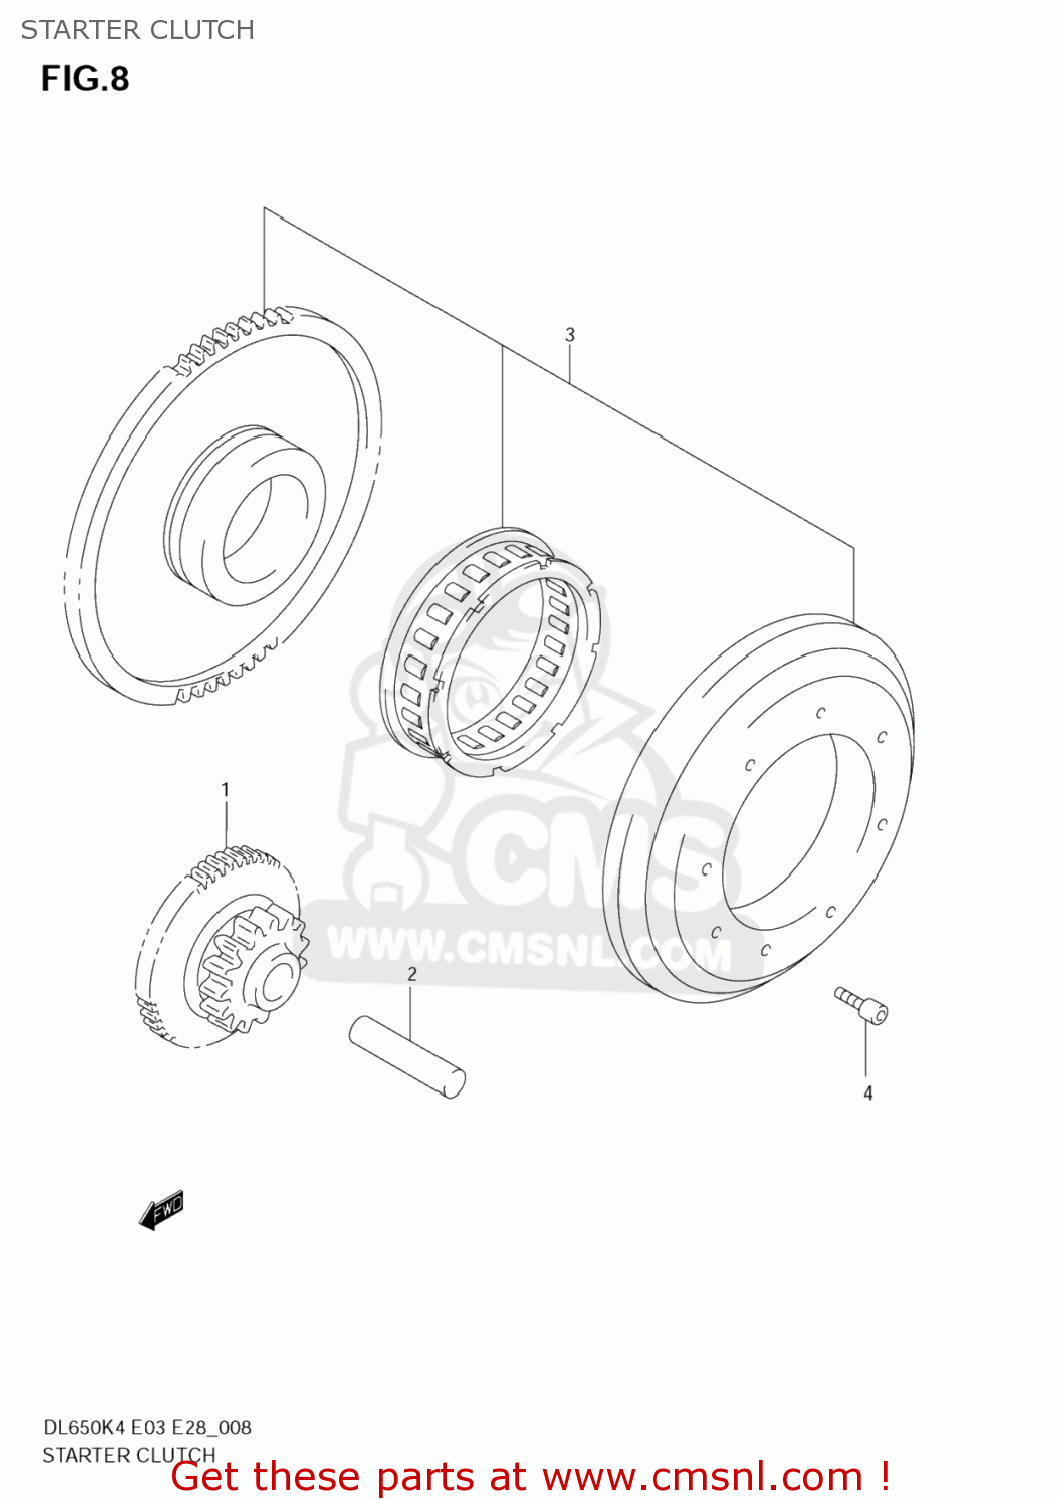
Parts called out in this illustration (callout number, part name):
1	GEAR,STARTER IDLE
2	PIN(8X12X45.5)
3	CLUTCH SET,STARTER
4	BOLT(8X16)
